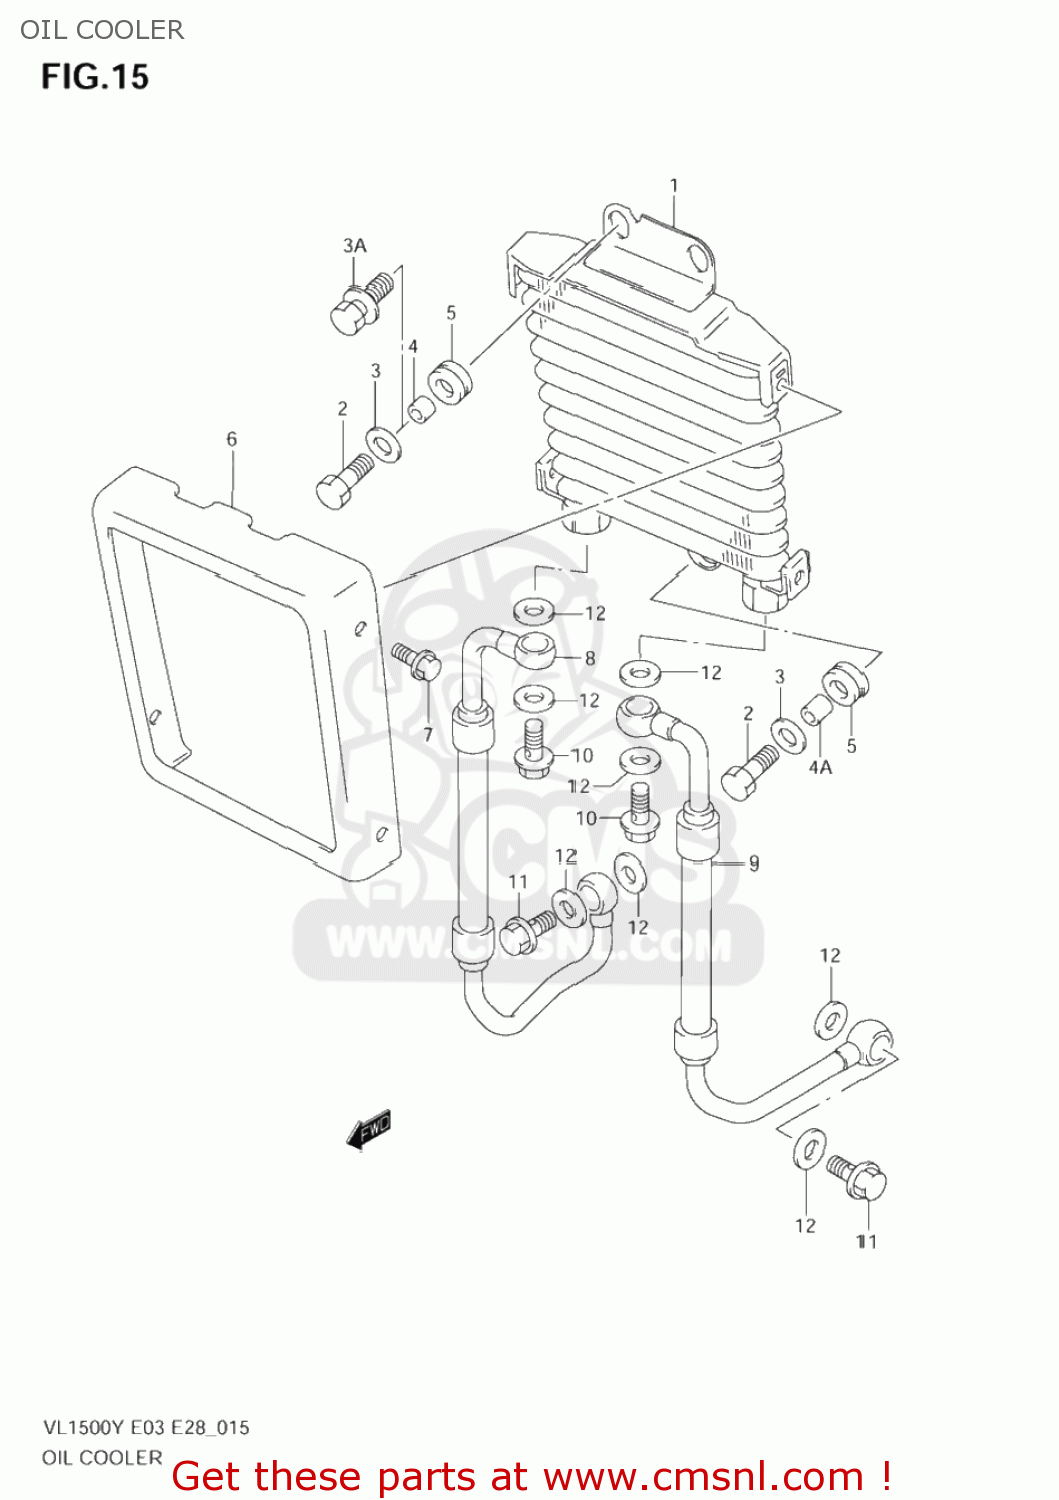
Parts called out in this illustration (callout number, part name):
1	COOLER ASSY,OIL
2	BOLT
3	WASHER(6.5X20X1.2)
3A	BOLT(6X20)
4	SPACER(6.5X10X10)
4A	SPACER(6.5X10.5X12)
5	CUSHION
6	COVER,OIL COOLER
7	SCREW(6X12)
8	HOSE,OIL COOLER,R
9	HOSE,OIL COOLER,L
10	BOLT UNION
11	BOLT UNION
12	GASKET(14X20X1.5) (NAS)
